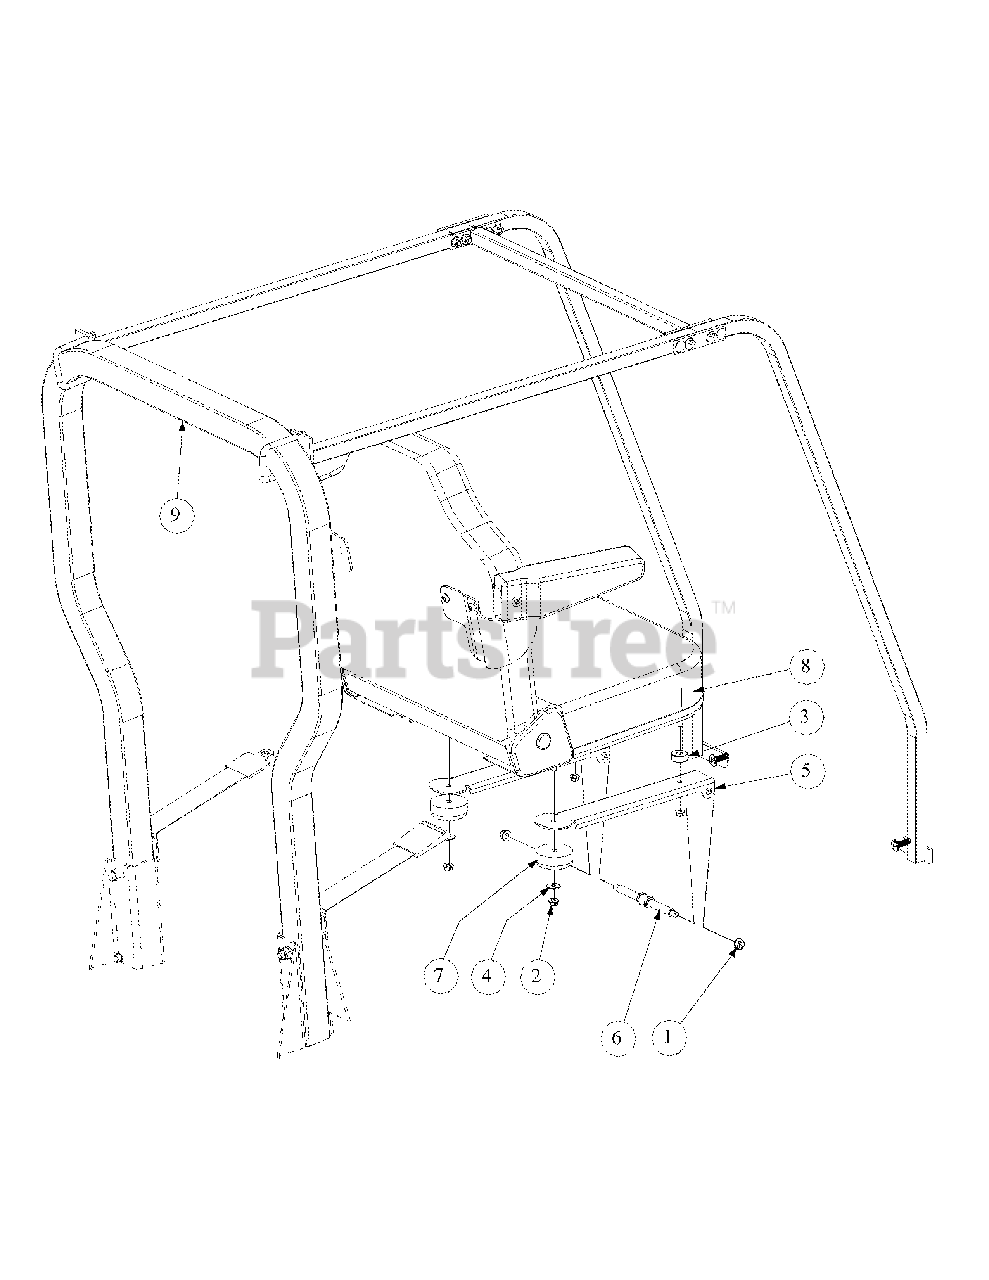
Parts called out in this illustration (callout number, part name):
1	Nut, Hex 3/8-16 Flange Lock
2	Lock Nut, Hex Flange, 5/16-18
3	Spacer, 0.345 ID x 1.50 OD x .41
4	Washer, .325 ID x .930 OD x .045
5	Mounting Bracket, Seat
6	Shoulder Screw, .50x2.345, 3/8-16
7	Grommet, 2.5 OD x 1.0 Long
8	Adjustable Seat, Black embossed, Forward Fold
9	Rops Assembly
